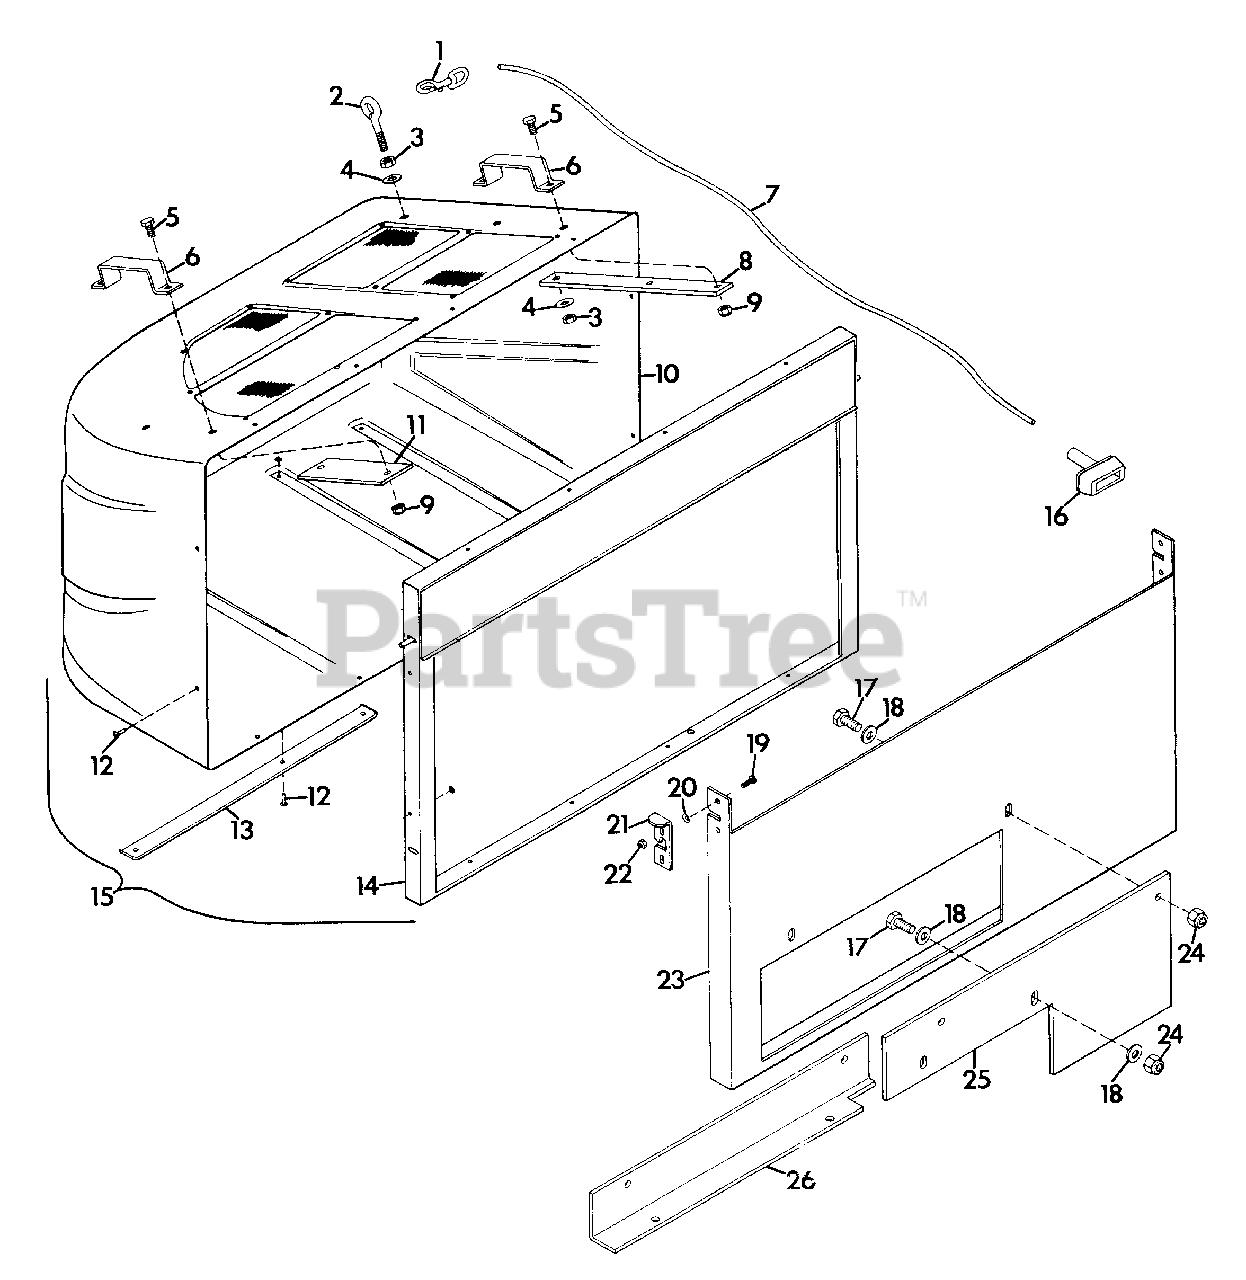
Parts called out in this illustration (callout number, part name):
1	SNAP, SWIVEL
2	BOLT, EYE
3	NUT, HEX 5/16-18
4	WASHER, FLAT .312X.734X.065
5	BOLT, HEX 1/4-20X1.00
6	HANDLE, HOPPER
7	ROPE, #6X66" LONG
8	STRAP
9	NUT, LOCK 1/4-20
10	HOPPER W/SCREENS, CAUTION DECAL
11	PLATE, BRACE
12	RIVET, POP .125X.357
13	PLATE, SKID
14	FRAME, HOPPER
15	HOPPER/FRAME, COMPLETE
16	HANDLE
17	BOLT, HEX 3/8-16X1.00
18	WASHER, FLAT .406X.812X.065
19	SCREW
20	1/4" SPRING WASHER
21	LATCH, CATCHER LEFT
22	NUT, LOCK 10-24
23	SUPPORT, GRASS CATCHER
24	NUT, LOCK 3/8-16
25	ADAPTOR, PRO 40
26	ADAPTOR, PRO 36
NS	LATCH, CATCHER RIGHT
